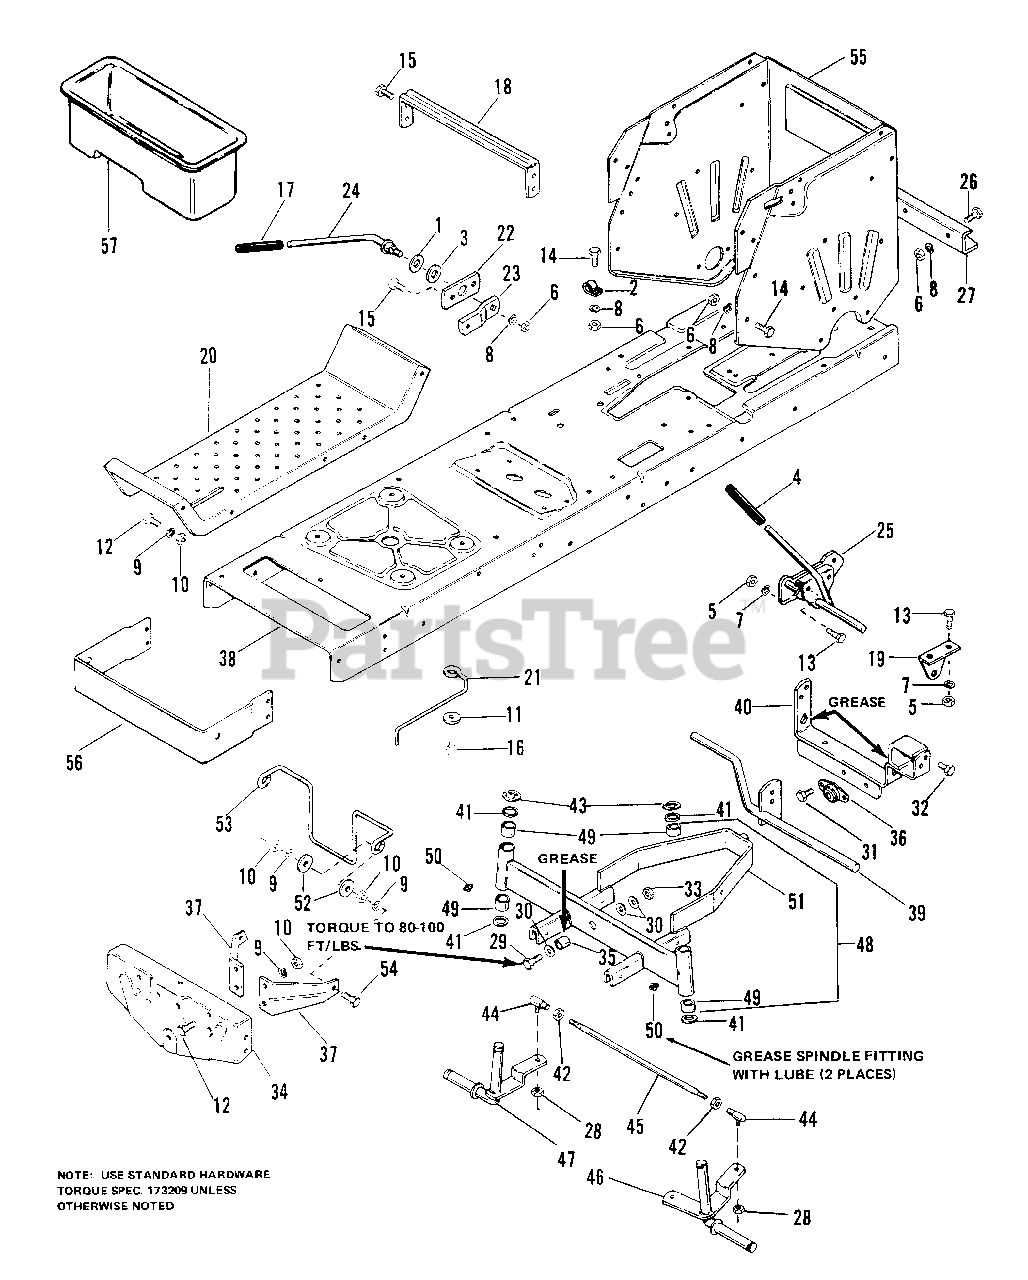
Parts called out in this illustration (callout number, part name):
1	WASHER, Steel
3	WASHER, Nylon
4	HANDLE, Grip
5	NUT, Hex, 1/4-20
6	NUT, Hex, 3/8-16
7	LOCKWASHER, Spring, 1/4
8	LOCKWASHER, Spring, 3/8
9	LOCKWASHER, Spring, 5/16
10	NUT, Hex, 5/16-18
11	WASHER, Plain, 5/16
12	CAPSCREW, Hex Hd., 5/16-18 x 3/4
13	CAPSCREW, Hex Hd., 1/4-20 x 5/8
14	CAPSCREW, Hex Hd., 3/8-16 x 3/4
15	SCREW, Tapping, 5/16-18 x 1/2
16	SCREW, Tapping, 5/16-18 x 7/8
17	GRIP
18	BRACE, Seat
19	SUPPORT, Clutch
21	STOP, Belt
22	BAR, Support
23	ARM, Lift
24	HANDLE, Lift
25	LEVER ASSY, Clutch
26	CAPSCREW, Hex Hd., 3/8-16 x 1
27	BAR, Draw
28	LOCKNUT, 3/8-24
29	CAPSCREW, Hex Hd., 1/2-13 x 1-1/2 Gr. 8
30	WASHER, Plain, 9/16
31	SCREW, Washer Hd., 3/8-16 x 1/2
32	SCREW, Hex Washer Hd., 5/16-18 x 5/8
33	LOCKNUT, 1/2-13
34	FRONT AXLE SUPPORT
36	BEARING ASSY, Side Range
37	BRACE, front Axle
39	LEVER ASSY, Brake
40	SUPPORT ASSY, Axle
42	NUT, Hex Jam, 3/8-24
43	KLIPRING, .75 Dia Shaft
44	BALL JOINT ASSY
46	SPINDLE ASSY, L.H.
47	SPINDLE ASSY, R.H.
48	AXLE ASSY, Front (Includes Ref. Nos. 49 & 51)
50	FITTING, Lube
51	FRONT AXLE, w/o Bushings
52	WASHER, Plain, 1/4
53	STOP, Belt
54	CAPSCREW, Hex Hd., 5/16-18 x 1-1/2
55	SUPPORT, Axle (Rear Frame)
56	SUPPORT (Model 4108 ES)
56	SUPPORT (Model 4111)
57	TOOL TRAY (4111 Only)
